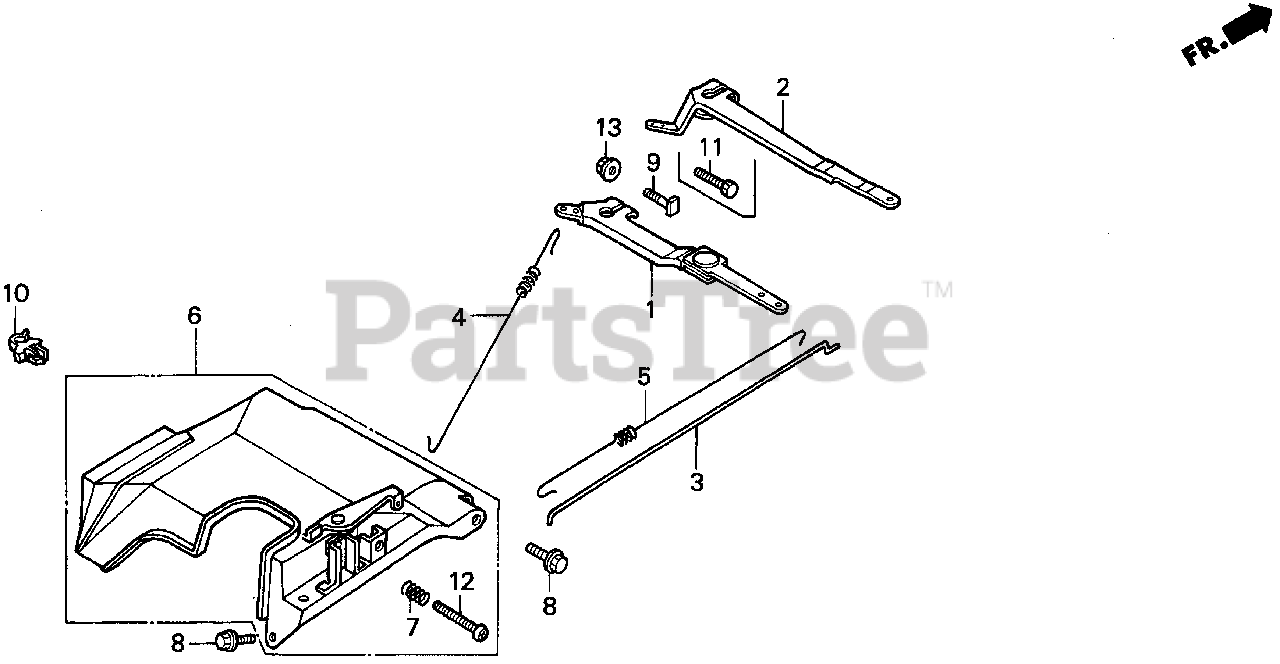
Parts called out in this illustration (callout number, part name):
2	ARM, GOVERNOR
3	ROD, GOVERNOR
4	SPRING, GOVERNOR (L=145.0MM) (WIRE DIAMETER 1.0MM)
5	SPRING, THROTTLE RETURN
6	CONTROL ASSY.
7	SPRING, CONTROL ADJUSTING Use from Engine SN 2327377.
8	BOLT, FLANGE (6X12) (CT200)
9	BOLT, GOVERNOR ARM
11	BOLT, HEX. (6X22)
12	SCREW, PAN (5X35)
13	NUT, FLANGE (6MM)
